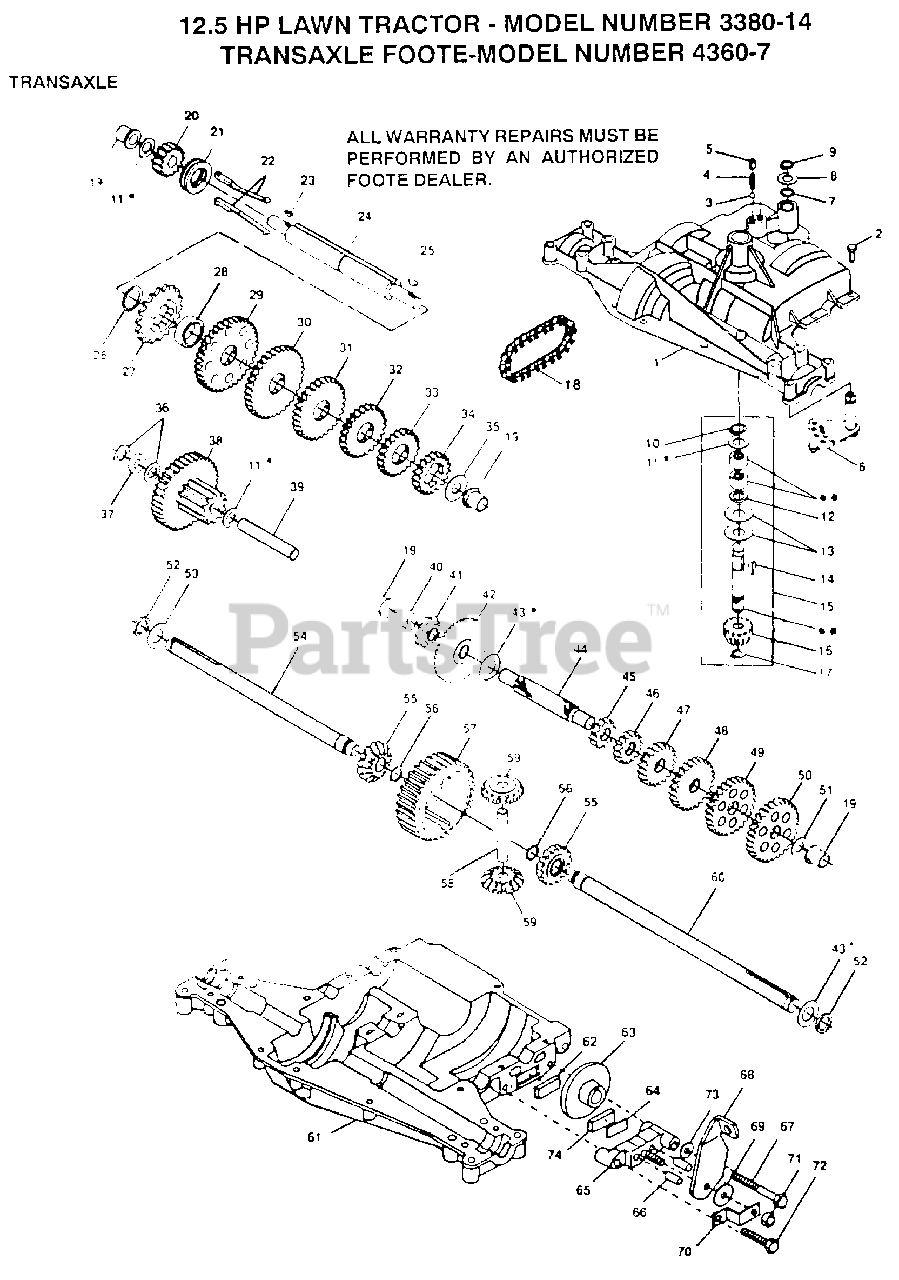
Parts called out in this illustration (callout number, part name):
1	HOUSING UPPER
3	BALL DETENT
4	SPRING, DETENT
5	SCREW, SET
6	ASSY SHIFTER
8	WASHER PLAIN
9	RING RETAINING
10	RING RETAINING
11	WASHER PLAIN
11	WASHER, PLAIN .632 X 1.00 X .026
11	WASHER, PLAIN .632 X 1.00 X .060
13	WASHER, PLAIN .632 X 1.38 X .046
14	KEY WOODRUFF #9
15	ASSY KIT INPUT SHAFT
16	PINION, BEVEL, 14 TEETH
17	RING, RETAINING
18	CHAIN, 24 PITCHES
19	BEARING, FLANGE
20	GEAR SPUR, 14 TEETH
21	COLLAR CLUTCH
22	KEY CLUTCH
23	KEY WOODRUFF #3
24	SHAFT INTERMEDIATE
25	KEY, WOODRUFF, #61
26	RING, RETAINING
27	SPROCKET, 18 TEETH
29	GEAR, SPUR, 37 TEETH
30	GEAR, SPUR, 35 TEETH
31	GEAR, SPUR, 30 TEETH
32	GEAR, SPUR, 25 TEETH
33	GEAR, SPUR, 22 TEETH
35	WASHER, PLAIN .640 X 1.37 X .061
36	WASHER, PLAIN .632 X 1.00 X .026
37	SPACER .630 X 1.00 X .169
38	ASSY GEAR COMB 12&35 TEETH
39	SHAFT IDLER
40	SPACER .635 X .875 X .755
41	SPROCKET, 9 TEETH
42	GEAR, BEVEL, 42 TEETH
43	WASHER PLAIN
43	WASHER, PLAIN .758 X 1.25 X .031
44	SHAFT, DRIVE
45	GEAR, SPUR, 12 TEETH
46	GEAR SPUR, 15 TEETH
47	GEAR, SPUR, 20 TEETH
48	GEAR, SPUR, 25 TEETH
49	GEAR, SPUR, 28 TEETH
50	GEAR, SPUR, 31 TEETH
51	WASHER, PLAIN .632 X 1.00 X .060
53	WASHER PLAIN
54	AXLE LEFT HAND
55	GEAR, MITER, 15 TEETH
56	RING, RETAINING
57	GEAR, SPUR, 32 TEETH
58	SHAFT, CROSS
59	GEAR, MITER, 15 TEETH
60	AXLE, R.H.
61	HOUSING LOWER
62	PUCK, FRICTION
63	DISC, BRAKE
65	JAW, BRAKE
66	PIN, DOWEL
67	SCREW TAPPING
68	LEVER, ACTUATING
69	WASHER, PLAIN .321 X 1.00 X .055
70	BRACKET, ANTI-ROTATION
71	LOCKNUT 5/16-24
72	SCREW TAPPING
73	WASHER PLAIN
74	PUCK, FRICTION
